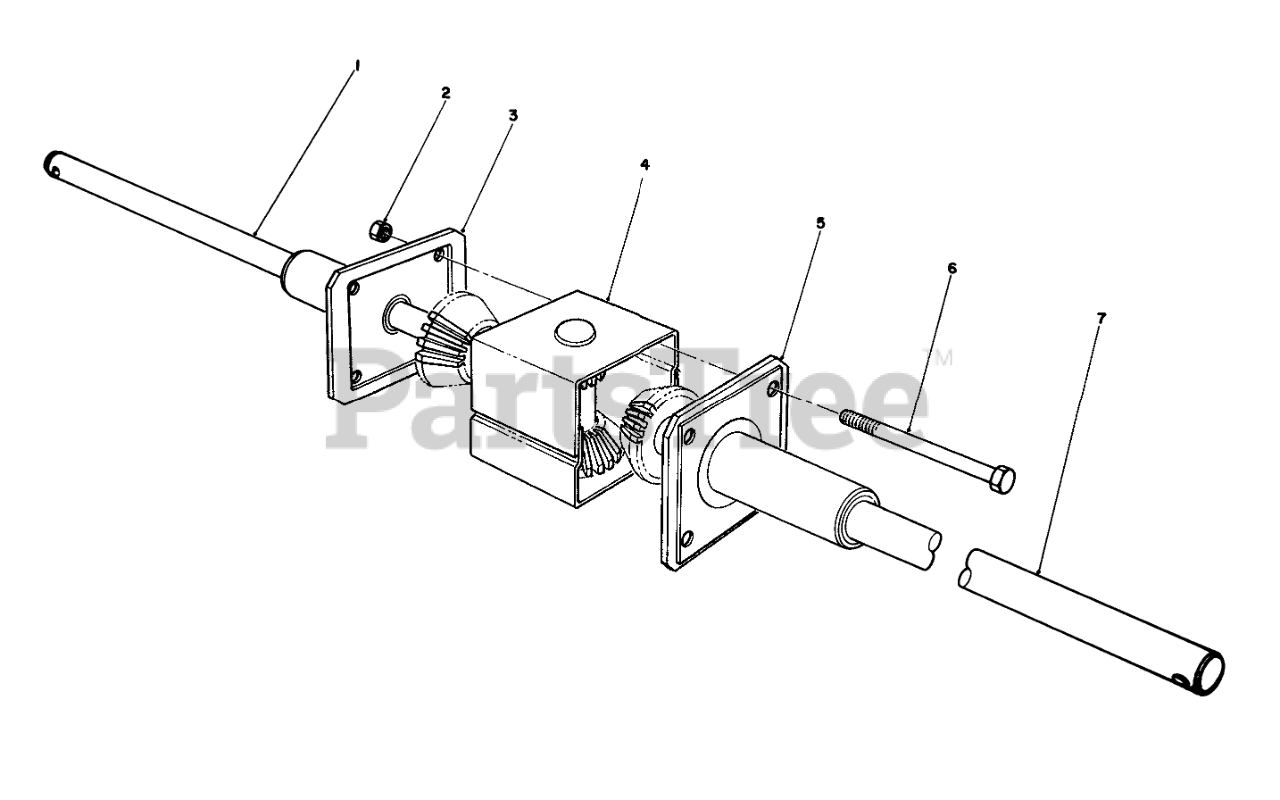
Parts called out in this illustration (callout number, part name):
2	NUT-LOCK, CONE
3	END CAP/BRG ASM
4	GEAR CASE ASM
5	END CAP &BEARING ASY
6	SCREW-HH
